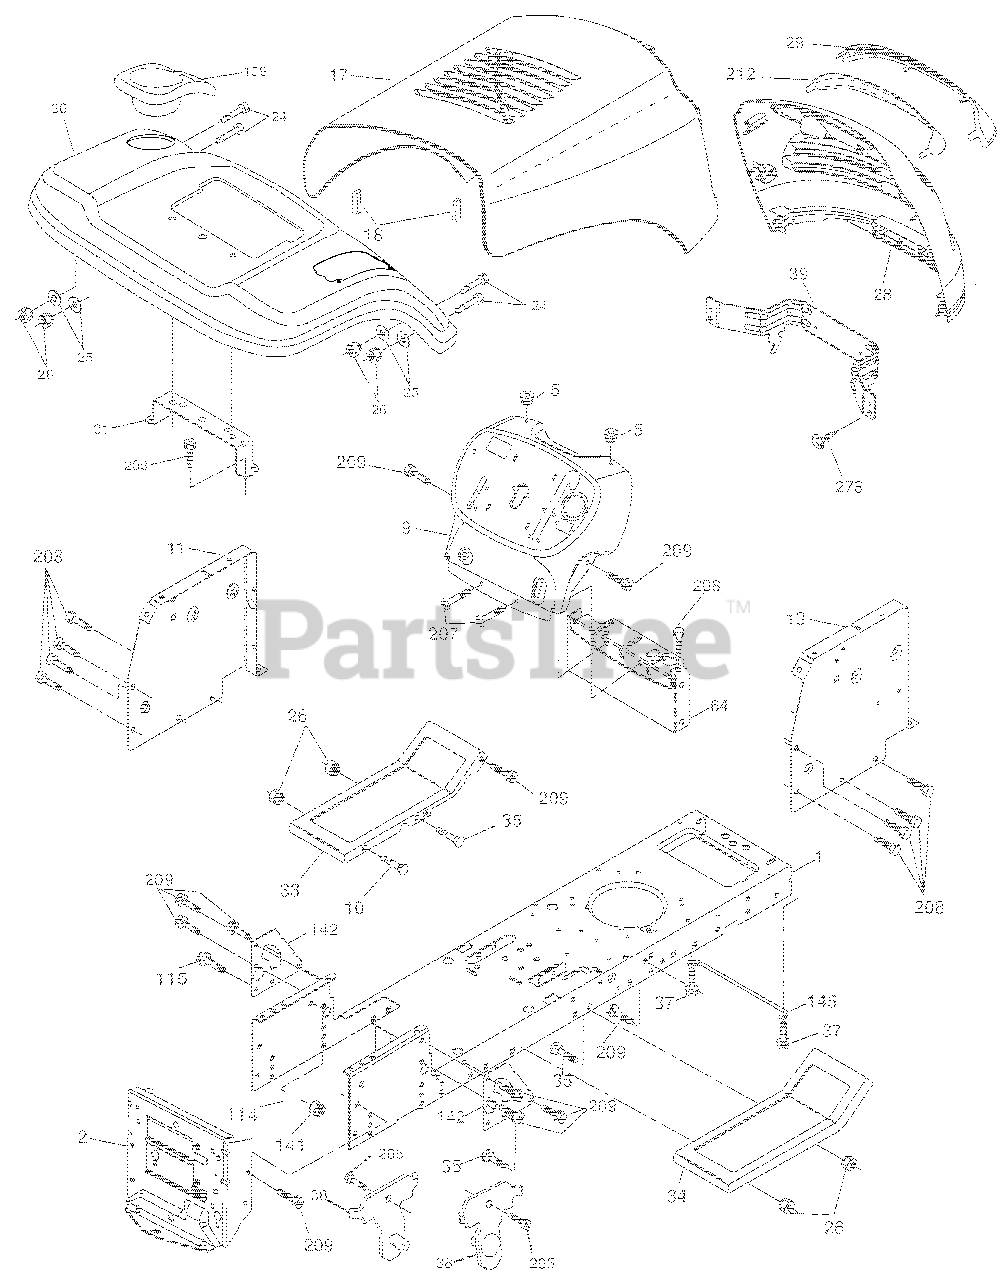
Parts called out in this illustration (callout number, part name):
1	Chassis
2	Drawbar, Stretch
5	Bumper, Hood/Dash
10	Panel Slkscr Dash RH
11	Panel Dash LH
13	PANEL.SLKSCR.DASH.RH
18	BUMPER.HOOD.LARGE. 1.75"
24	Bolt Fin Hex 3/8-16 unc x 1 Gr
25	Washer 13/32 x 13/16 x 12 Ga.
26	Locknut, Washer Insert 3/8-16
29	LENS.GRILLE.BAR
30	FENDER
31	Bracket Fender Repl 109873X
33	FOOTREST LH
34	FOOTREST RH
35	Bolt Rdhd Sht Sqnk 3/8-16 x 3/
37	SCREW.THDROL.5/16-18 X 1/2TYTT
38	Bracket Asm. Pivot Mower
39	Bracket Pivot
64	Dash Lower
114	KEEPER.BELT.REAR
115	Screw 3/8-16 x <
141	Nut, Hex, Flangelock 3/8-16
142	Plate Reinforcement
145	ROD.PIVOT.HOOD
159	CUPHOLDER
205	Screw Thdrol 3/8-16 x 1/2
207	Screw 5/16-18 x 1/2
208	SCREW.THDROL.3/8-16X1/2.TYT.BL
209	SCREW.HEXWSH THDR3/8-16X3/4.BL
212	Insert Lens Reflect
